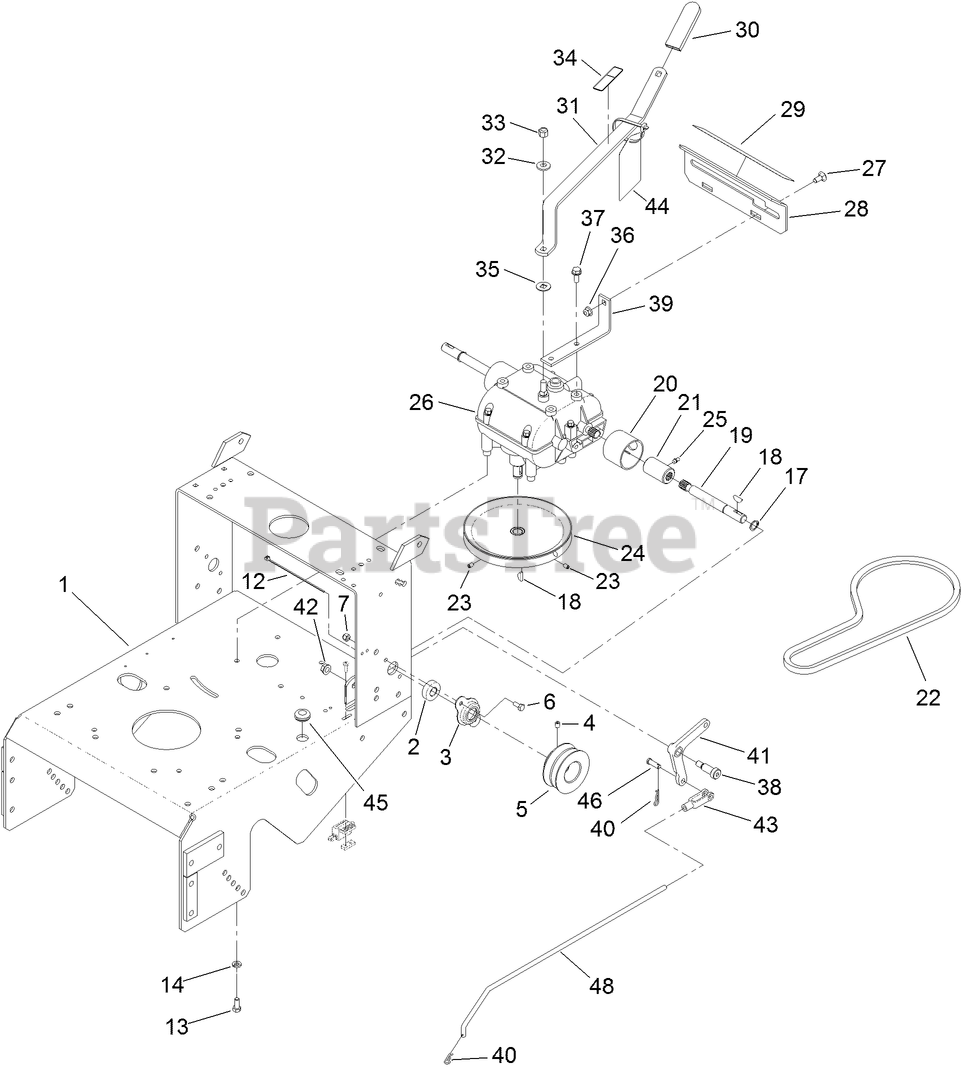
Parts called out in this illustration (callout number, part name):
1	FRAME-GEAR
2	BEARING-SHAFT
3	FLANGE-OUTPUT
4	SETSCREW
5	SHEAVE-TRANSMISSION
6	SCREW-HH
7	NUT-LOCK, NI
12	TIE-CABLE
13	SCREW-HH
14	WASHER-LOCK
17	RING-RETAINING
18	KEY-WOODRUFF
19	SHAFT-TRANSMISSION
20	GUARD-COUPLER
21	COUPLER
22	V-BELT
23	SCREW-HSH
24	SHEAVE-TRANSMISSION
25	FITTING-GREASE
26	TRANSMISSION
27	BOLT-CARR
28	PLATE-SHIFT
29	DECAL-SPEED, GROUND
30	GRIP-LEVER
31	LEVER-SHIFT
32	WASHER-BELLEVILLE
33	NUT-LOCK
34	DECAL-CAUTION, GEARBOX
35	WASHER
36	NUT-HF, NI
37	SCREW-HWHTF
38	BOLT-SHOULDER
39	BRACKET-PLATE, SHIFT
40	PIN-COTTER
41	BELLCRANK
42	NUT-HHF, WHIZ
43	YOKE-ADJUSTABLE
44	HANG TAG-GEARBOX
45	GROMMET
46	PIN-CLEVIS
48	ARM-ASSIST, LINKAGE
